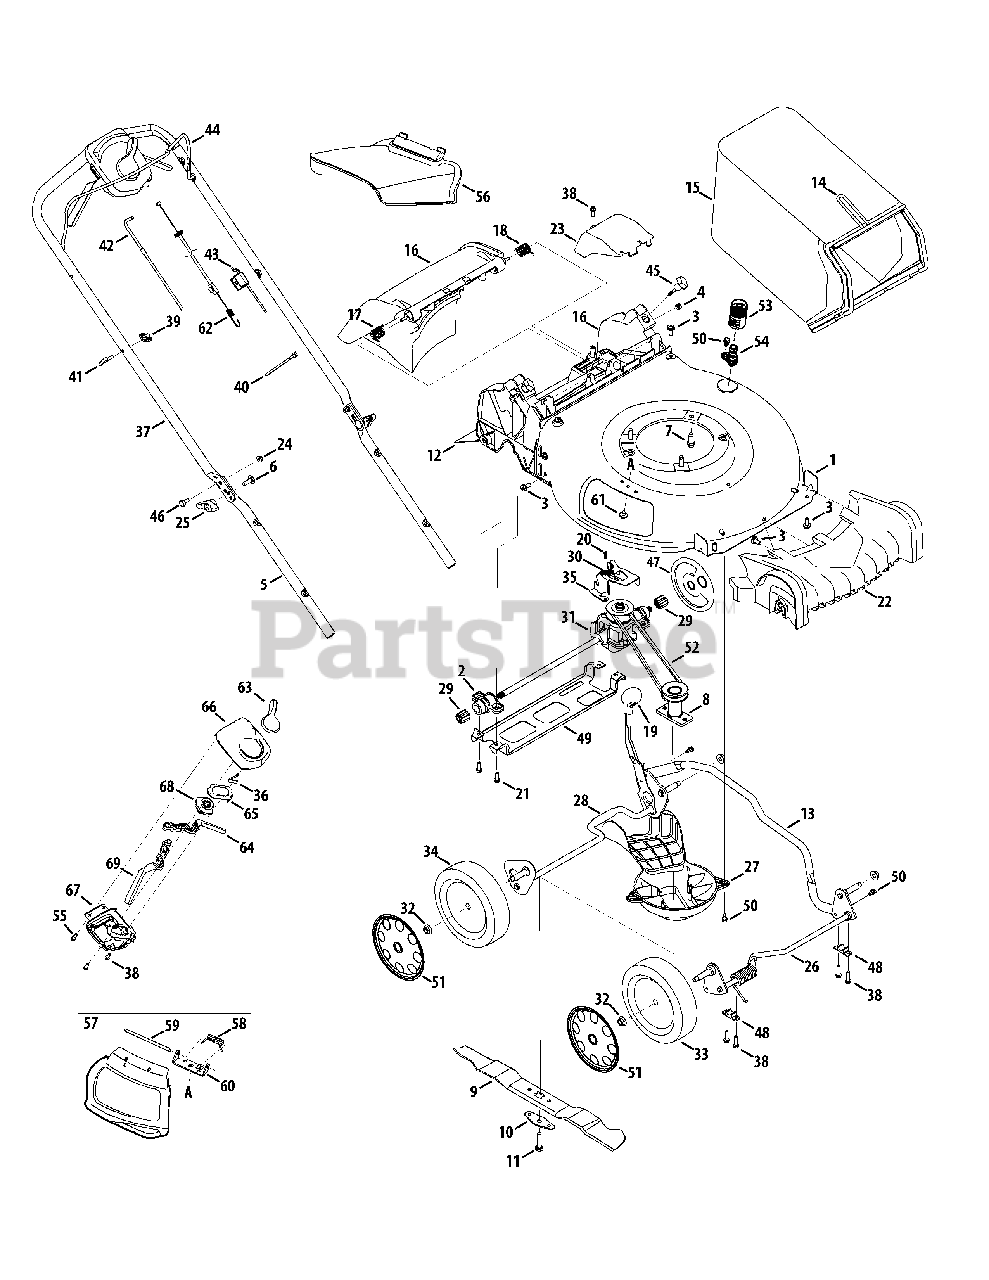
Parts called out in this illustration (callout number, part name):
2	Bearing Assembly
3	Screw, 5/16-14 x .750
4	Nut, Sq., 1/4-20
5	Lower Handle
6	Carriage Screw ,5/16-18
7	Screw, 3/8-16 x 1.00
8	Blade Adapter
9	Mulching Blade
10	Blade Bell Support
11	Screw, 3/8-24 x 1.50
12	Trailing Shield
14	Grass Catcher Frame
16	Rear Discharge Door Assembly
17	Torsion Spring - RH
18	Torsion Spring - LH
19	Adjustment Lever Knob
20	Screw, Hex Washer, .159 x .43
21	Screw, 1/4-15 x 1.25
22	Front Cover
23	Transmission Cover
24	Nut, Flange Lock, 1/4-20
26	Front Axle Assembly
27	Engine Baffle
28	Rear Axle Assembly
29	Spur Gear, 10T
30	Exten. Spring, 2.405
31	Transmission Assembly
32	Flange Lock Nut, 3/8-16
33	Front Wheel
34	Rear Wheel
35	Transmission Bracket
38	Screw, 1/4-15 x .750
40	Cable Tie
41	Rope Guide
42	Speed Adjustment Cable
43	Control Cable
46	Sldr. Screw, .375 x .126 x 1/4-20
47	Wheel Dust Cover
48	Bushing, Lock, .505 Dia. X .62
49	Rear Support Bracket
50	Shoulder Screw, 1/4-20 x 0.50
51	Hubcap, 8"
53	Water Nozzle Adapter
54	Water Nozzle
55	Scr., Shldr, 1/4-15 x .970
56	Side Discharge Chute
57	Mulch Plug (Incl. 58-60)
58	Torsion Spring
60	Chute Deflector Bracket
61	Screw, 1/4-20 x .500
62	Drive Cable
63	Speed Select Lever
64	Control Lever LH
65	Cable Adjust Plate
66	Upper Housing
67	Lower Housing
68	Speed Adjust Actuator
69	Control Lever RH
